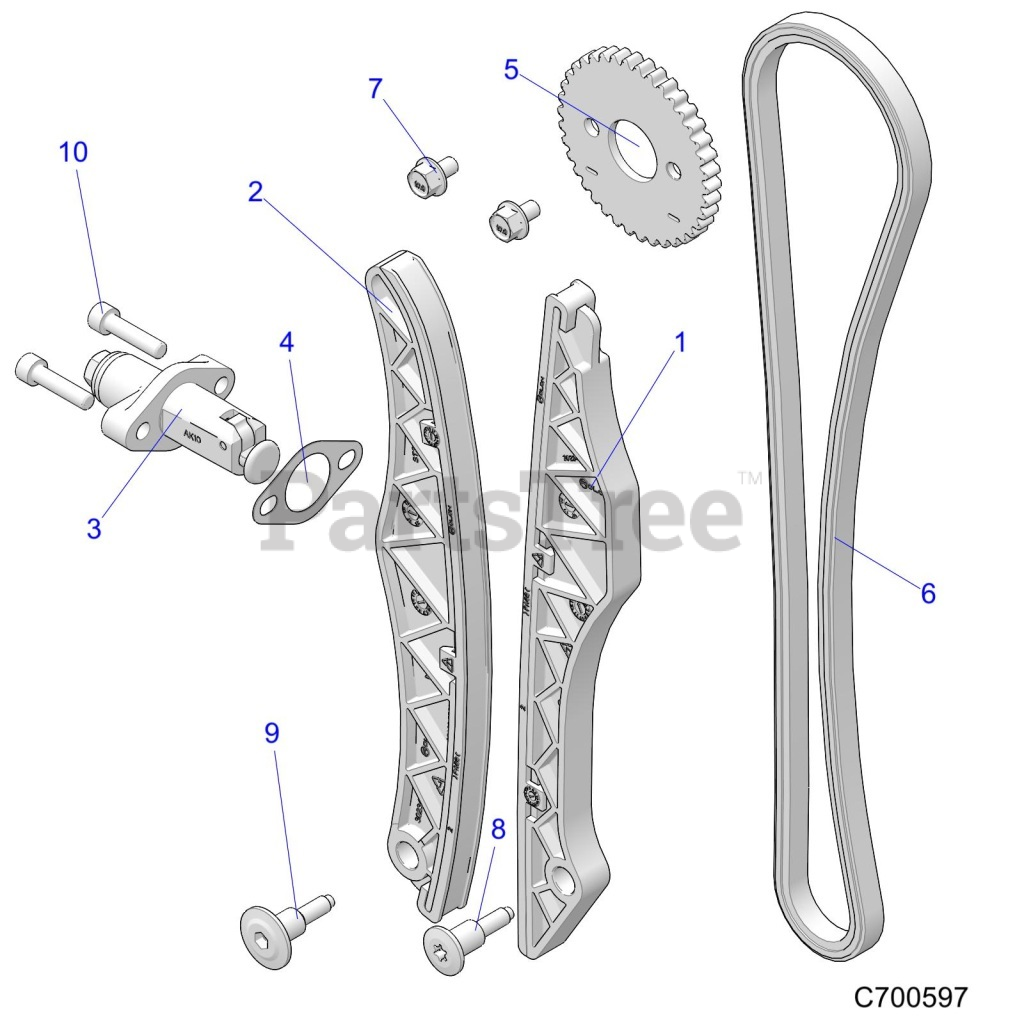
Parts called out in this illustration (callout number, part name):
1	GUIDE-CAM CHAIN,FIXED,SOHC
2	GUIDE-CAM CHAIN.TENSIONER,SOHC
3	TENSIONER-RATCHETING,MECH
4	GASKET, TENSIONER
5	SPROCKET-CAM,DRIVEN,SOHC
6	CHAIN-CAMSHAFT
7	SCR-HXFL,M6X1.0X10 10.9
8	BOLT-SHLDR,M6X12X15
10	SCR-SH-M6X1.0X25 10.9 ZPC D204
